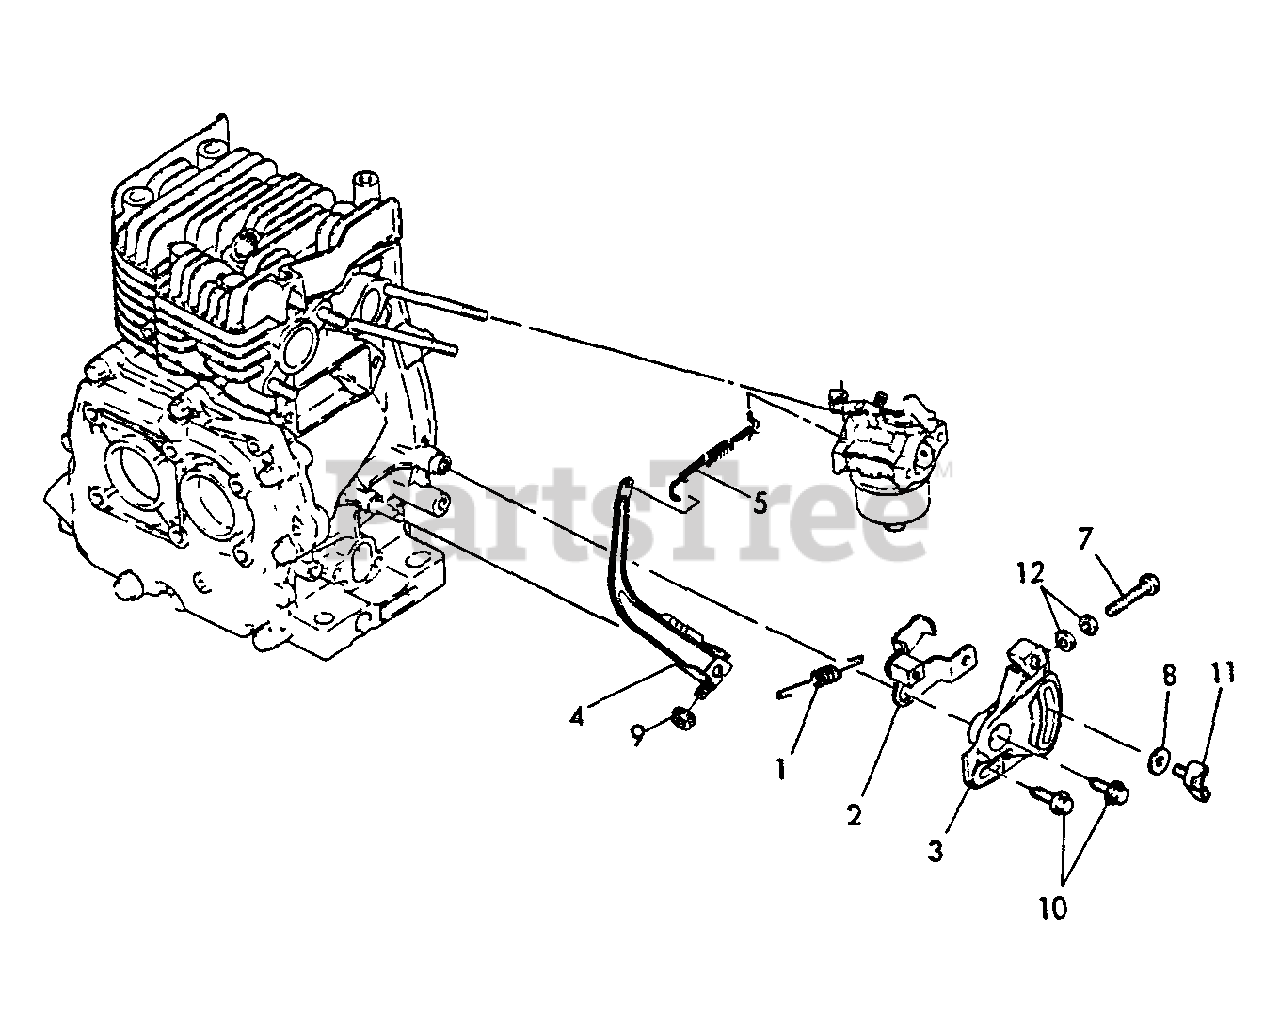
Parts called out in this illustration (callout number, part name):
1	SPRING, REGULATOR
2	HANDLE ASSY, REGULATOR
3	BRACKET, REGULATOR
4	LEVER, GOVERNOR
5	LINK, THROTTLE
6	SPRING, TENSION
7	BOLT
8	WASHER - 6
9	U-NUT M6
10	BOLT - 6×20
11	THUMBSCREW - 6×15
12	LOCKNUT - 6 -- PLATED
